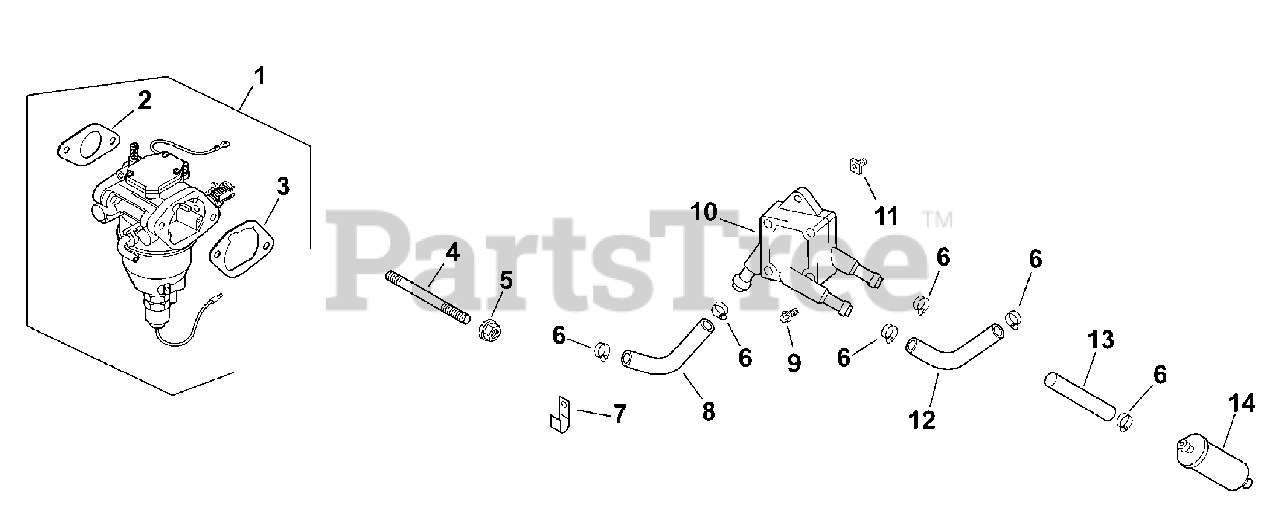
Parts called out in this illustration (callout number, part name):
1	KIT, CARBURETOR W/GASKET-NIKF
2	GASKET, CARBURETOR
3	GASKET, AIR CLEANER BASE
4	STUD,M6X1.0X128
5	NUT, FLG M6X1.0
6	CLAMP, HOSE (KM)-USE 25 237 31-S
7	CLIP, CABLE
8	LINE, FLEXIBLE FUEL 10.92"-USE 24 353 12
9	SCREW, TAP M6X1.7X18
10	PUMP, FUEL
11	NUT, PLASTIC (KM)-USE 25 100 37-S
12	LINE, FLEXIBLE FUEL 12.3"-USE 25 111 81-
13	LINE FLEXBLE FUEL (3.5" x.25") -USE 25 1
